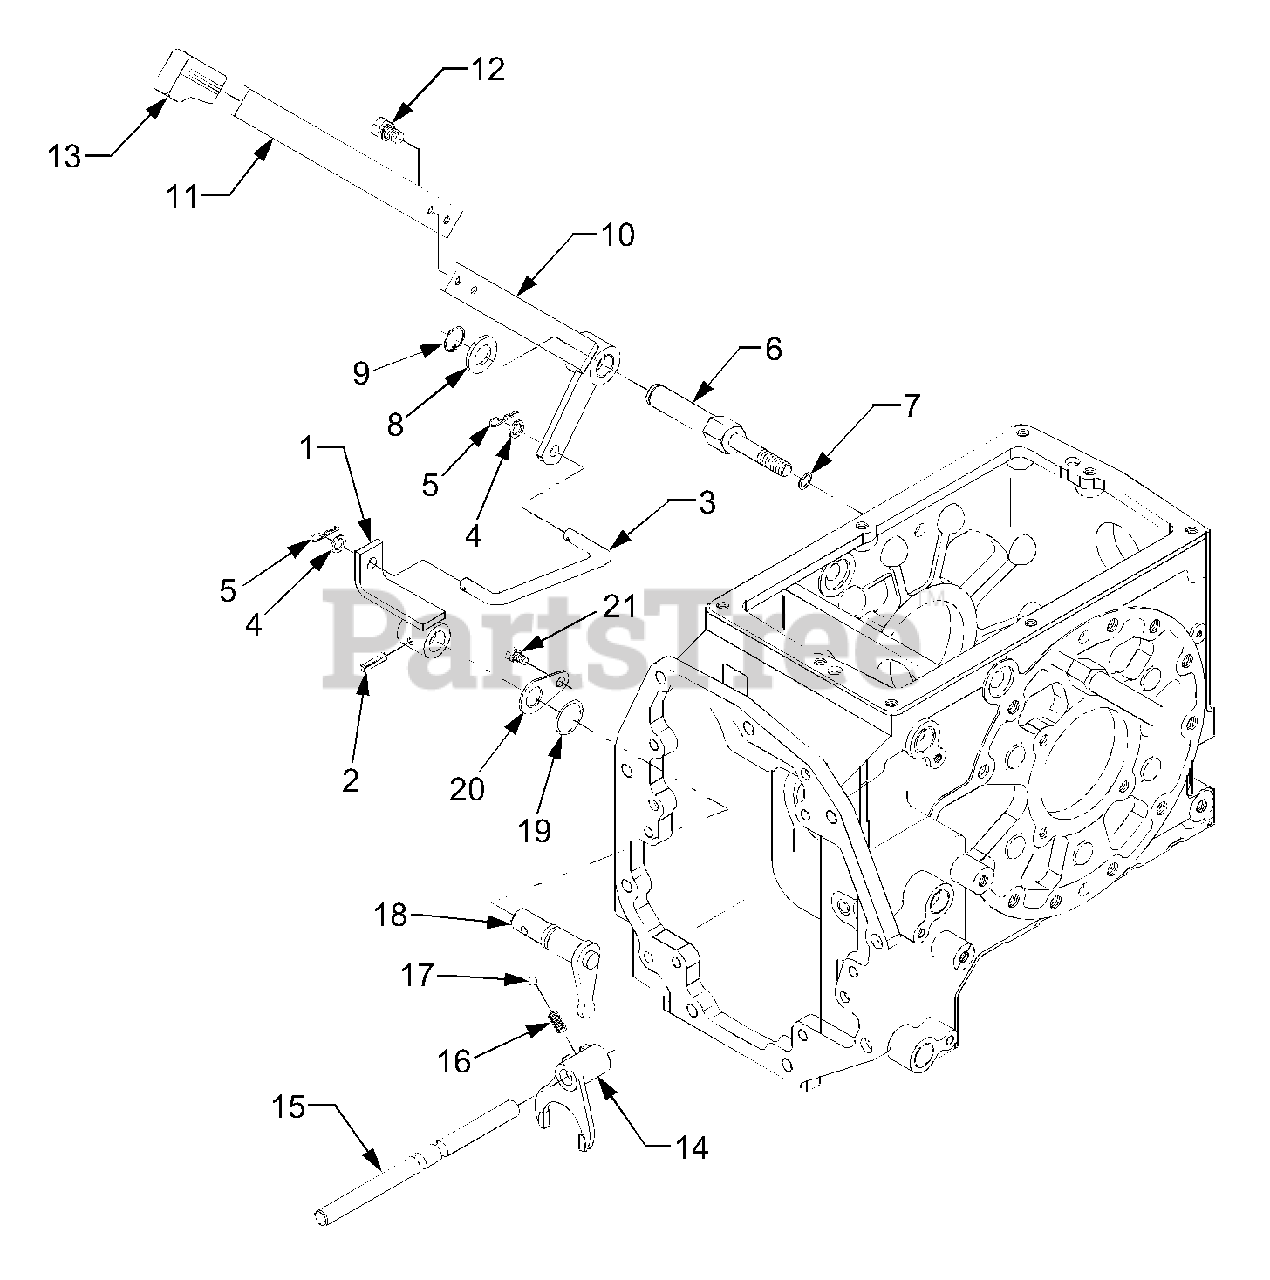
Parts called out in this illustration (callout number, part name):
1	Lever 1, Mid PTO
3	Rod (Mid PTO)
4	Washer, Plain
6	Shaft, Lever (Mid PTO)
7	Washer, Spring
8	Washer, Plain
10	Mid PTO Lever Ass'y
11	Lever, Mid PTO
14	Fork, Shift (Mid)
15	Rod, Fork (Mid)
